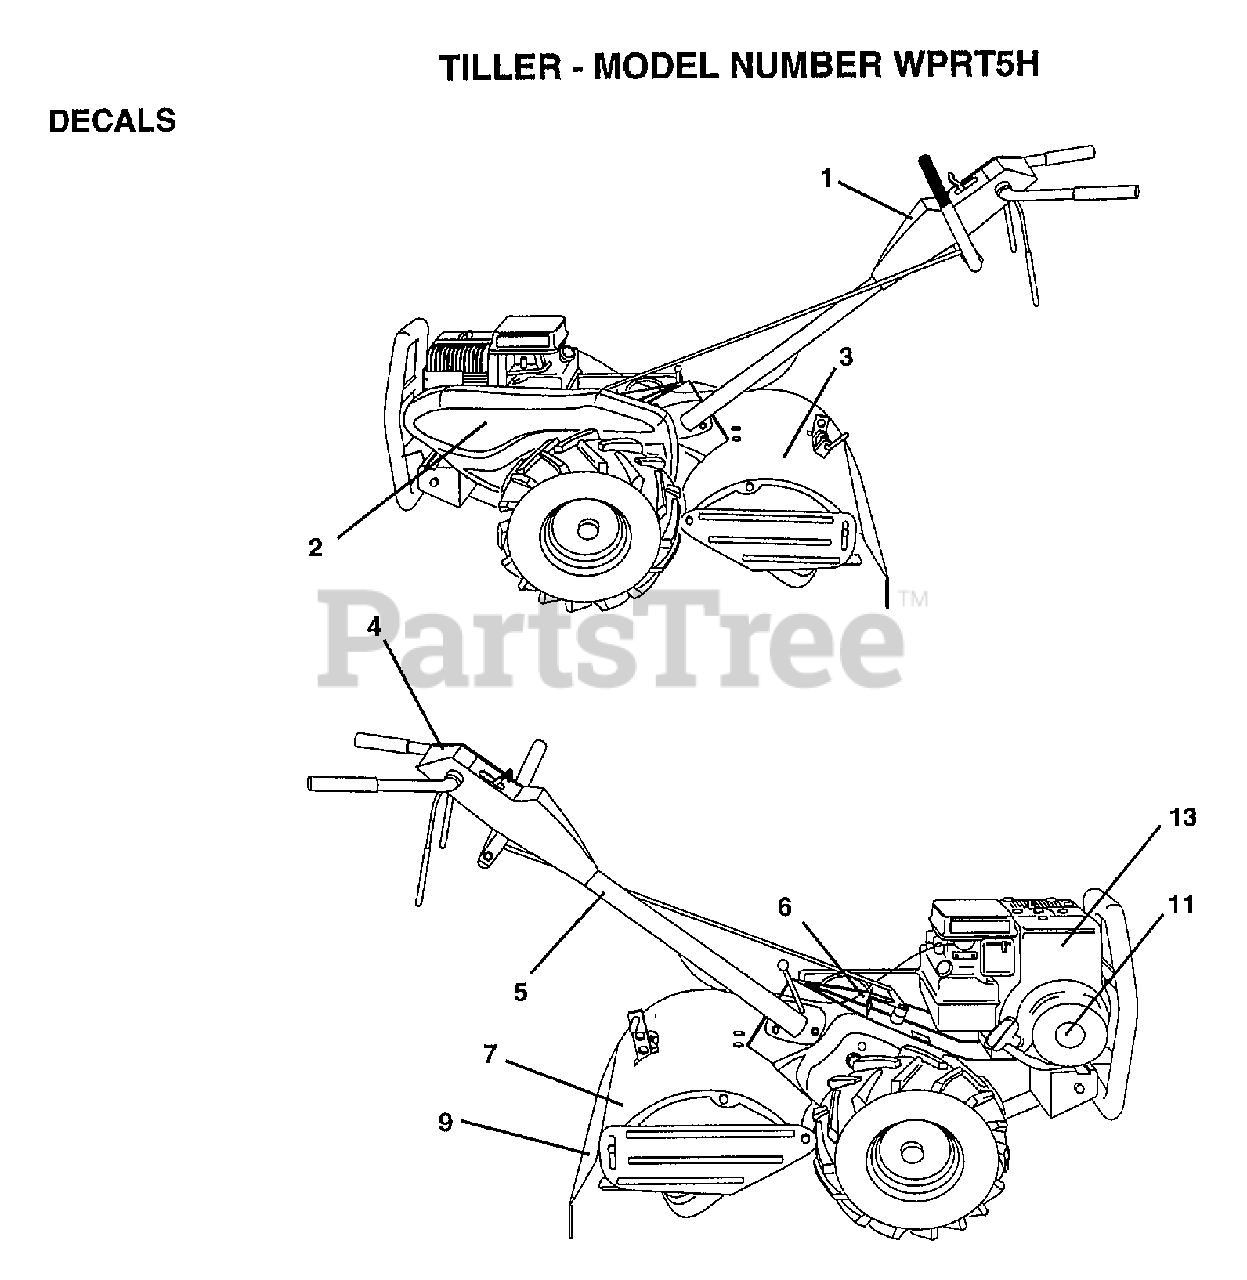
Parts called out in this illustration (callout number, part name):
1	DECAL.PNL.CONTROL
2	DECAL, LOGO
3	DECAL.SHLD.TINE
4	DECAL.INSTRUCTION
5	DECAL TI
6	DECAL CRT
7	DECAL.TINE.SHIELD
9	DECAL TI
